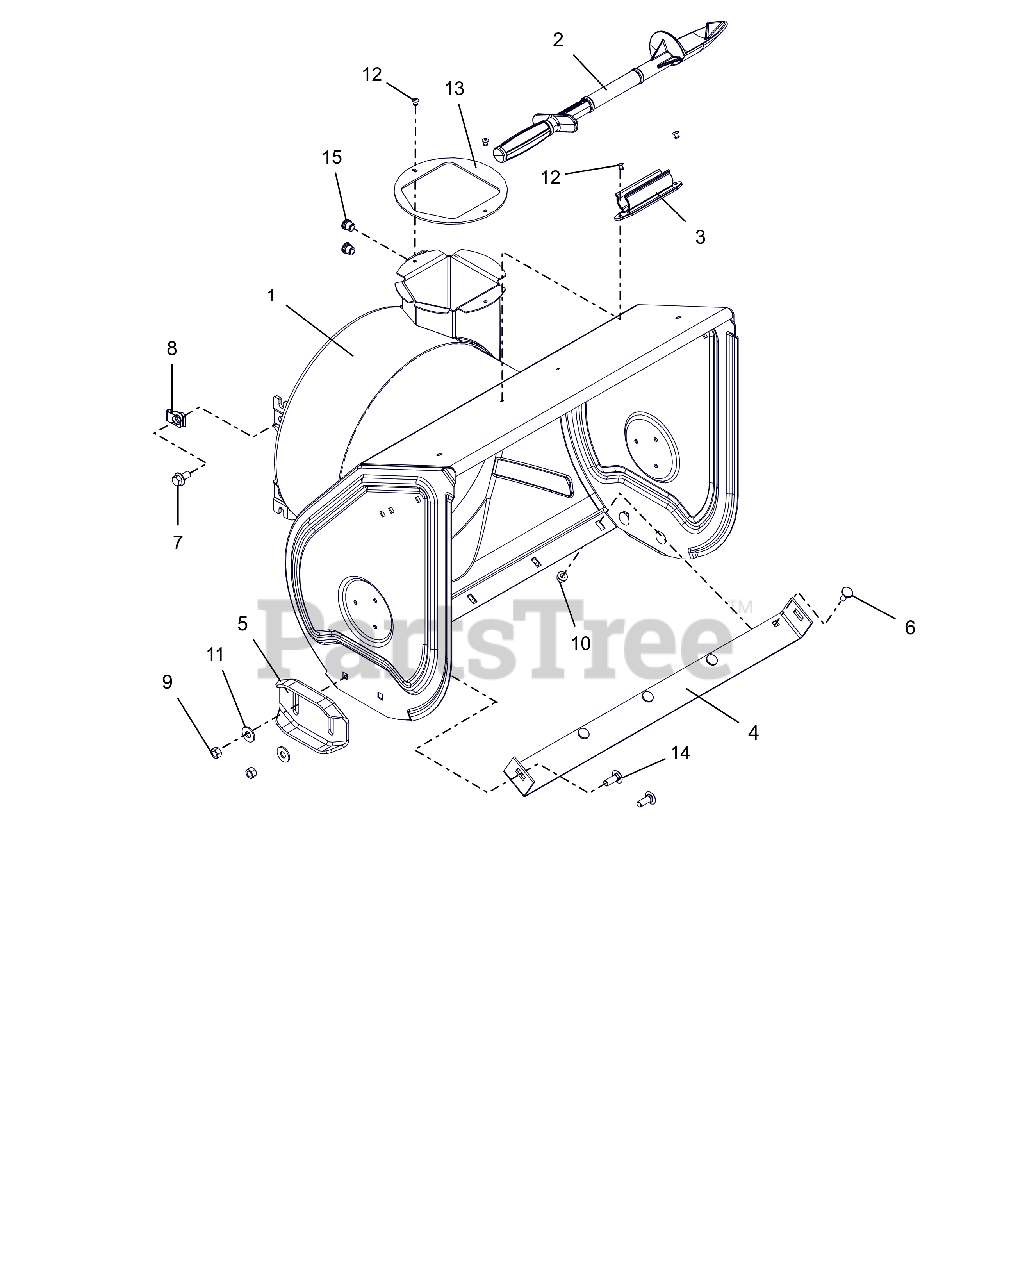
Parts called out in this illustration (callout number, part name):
1	BLOWER HOUSING W/DECAL 24"
2	DEVICE, SNOW CLEAN OUT
3	MOUNT, SNOW CLEAN OUT
4	BLADE, SCRAPER-24"
5	SKID SHOE, REVERSIBLE - ORANGE
6	BOLT, MODIFIED HEAD CARRIAGE
8	NUT-RTNR .375-16X.37
9	NUT-LK-CTR .38-16 ZC120
10	NUT-LK-TOP-FLG .312-18 GF ZCC
11	WSHR,FLT .438X1.00X.083 ZCC
12	RVT, POP .1875 ZCC
13	BAFFLE, DISCHARGE NECK
14	BLT,RHSSN .38-16X1.00 G5 ZCC
15	NUT,THD,INSERT .38-16 ZC120
